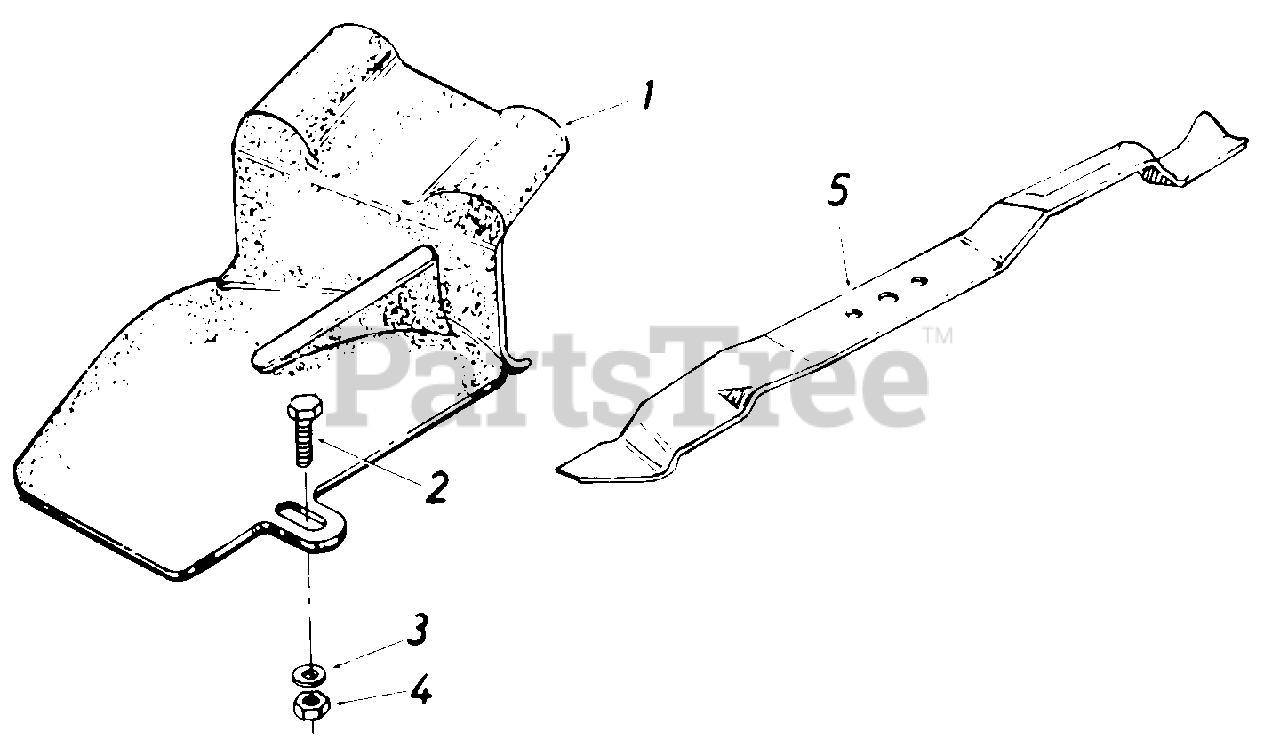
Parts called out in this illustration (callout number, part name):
1	Mulching Baffle
2	Hex Bolt 1/4-20 x .88" Lg.*
3	Belleville Wash. .265 I.D. x. .75 O.D. x .093
4	Hex Jam Nut 1/4-20 Thd.
5	20" Mulching Blade
